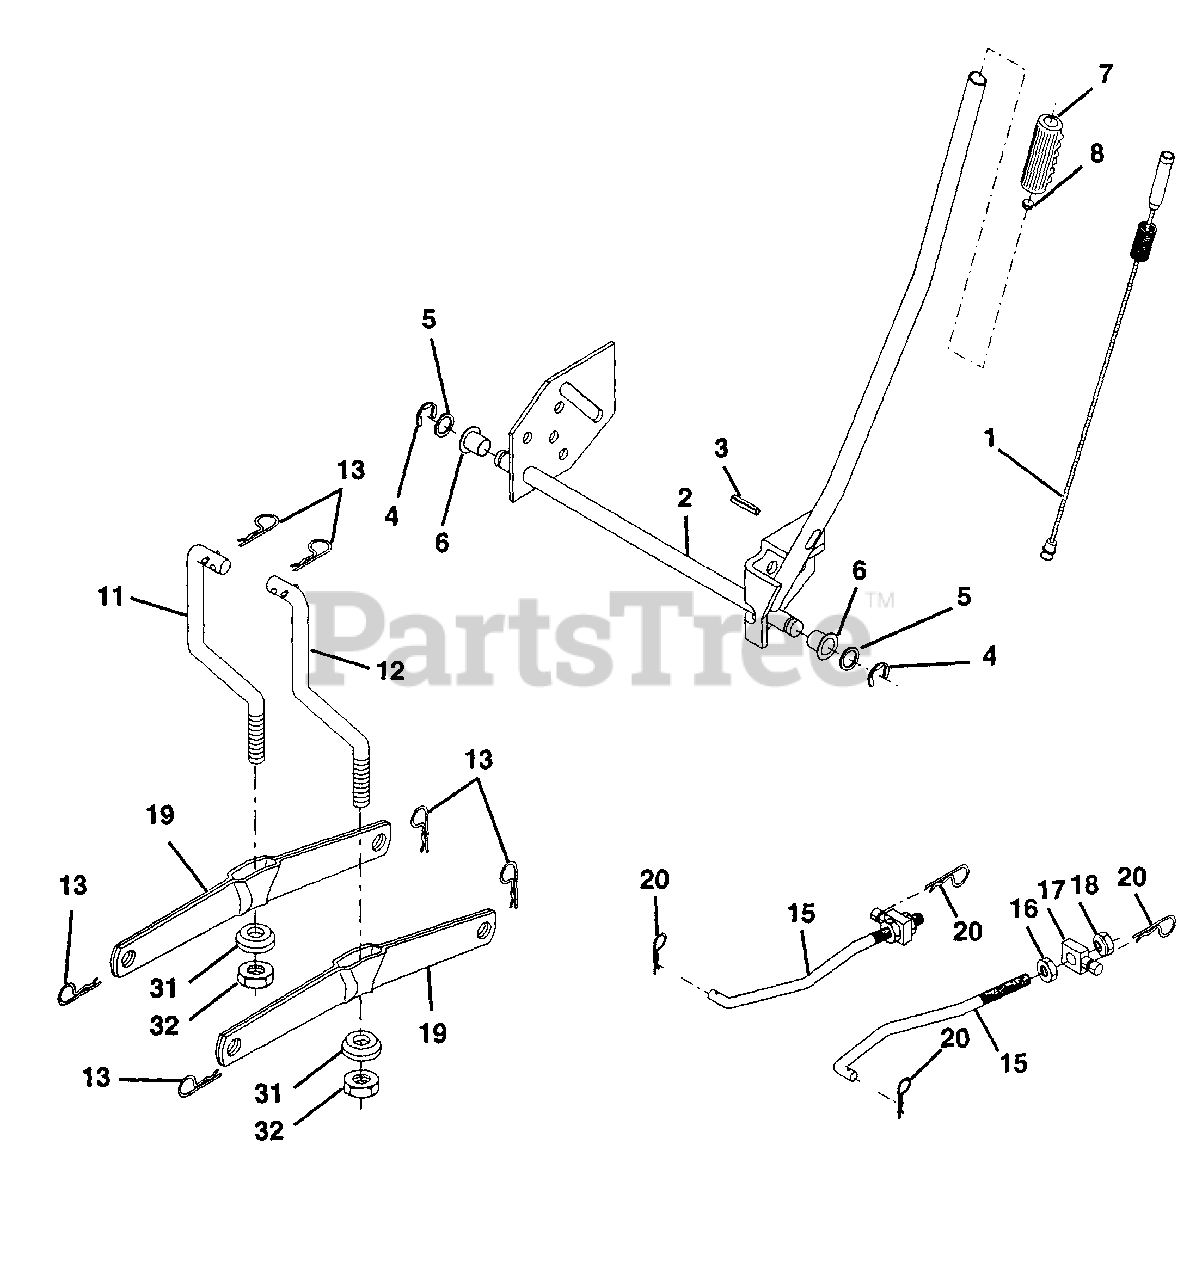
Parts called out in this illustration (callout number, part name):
1	Wire Asm Inner W/plunger
2	Shaft Asm Lift
3	Pin Groove
4	E Ring #5133-62
5	Washer PLTD 21/32 X 1 X 21ga
6	Bearing Nylon Blk 629 Id
7	Grip Handle Bicycle
8	Button Plunger Black
11	Link Lift LH
12	Link Lift RH
13	Retainer Spring
15	Link Front
16	Nut Jam Hex 1/2-13 Unc
17	Trunnion Blk Zinc
18	Nut Crownlock 1/2-13 Unc
19	Arm Suspension Rear
20	Spring, Retainer
31	Bearing Pvt. Lift Spherical
32	Nut Crownlock 3/8-24
